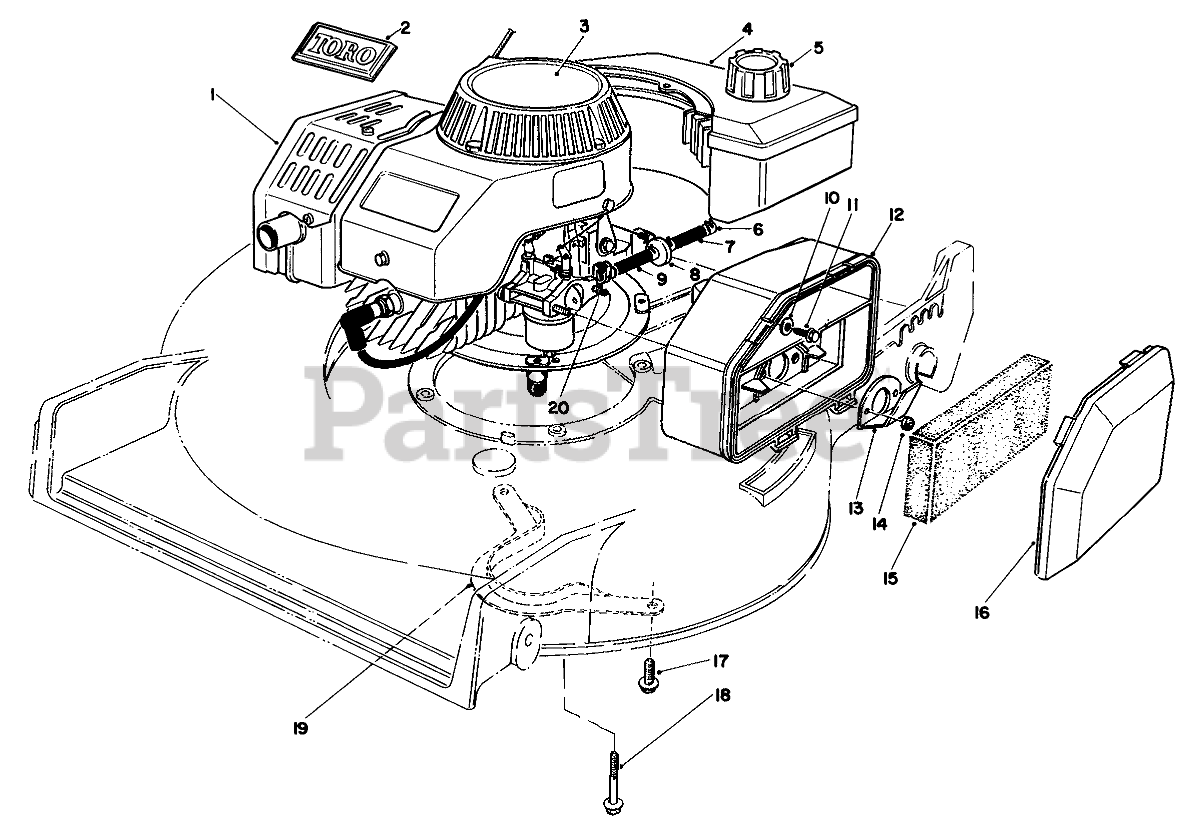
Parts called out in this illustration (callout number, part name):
1	Engine
2	TORO LOGO PLT
3	DECAL
4	Gas Tank Assembly
5	GAS CAP ASM
6	CLAMP-FUEL LINE
7	HOSE-FUEL
8	FILTER-FUEL
9	HOSE-FUEL
10	WASHER-FLAT
11	SCREW-HH
12	AIR CLEANER
13	SPIT BACK DEFLECTOR
14	NUT-LOCK
15	FILTER
16	AIR CLEANER COVER
17	Screw
18	SCREW-HHF
19	BBC BELT GUIDE
20	FUEL LINE CLAMP
